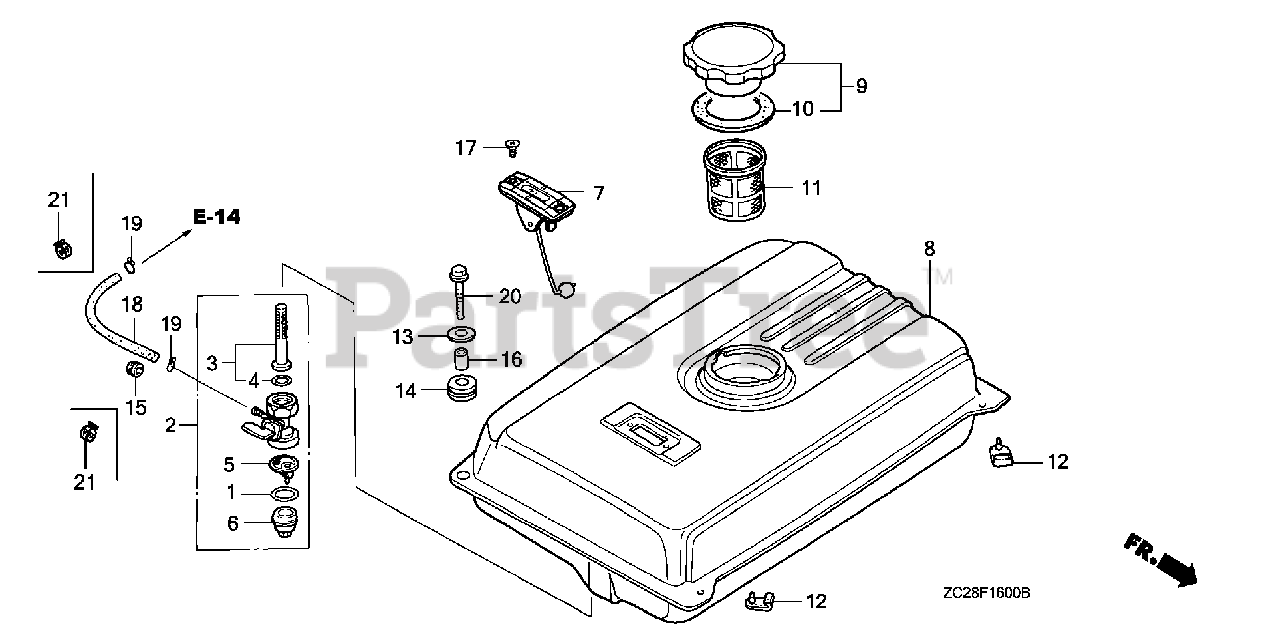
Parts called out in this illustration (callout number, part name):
1	GASKET, FUEL STRAINER CUP
2	PETCOCK ASSY.
3	SCREEN, FUEL STRAINER
4	O-RING (9X1.3)
5	FILTER, CUP
6	CUP, FUEL STRAINER
7	METER ASSY., FUEL
8	TANK, FUEL *R280* (POWER RED)
9	CAP, FUEL TANK
10	GASKET, FUEL FILLER CAP
11	FILTER, FUEL
12	RUBBER, TANK MOUNTING
13	WASHER, TANK RUBBER
14	CUSHION, TANK RUBBER
15	RUBBER, FUEL TUBE
16	COLLAR, TANK RUBBER
17	SCREW, FLAT (5X10)
18	BULK HOSE, FUEL (4.5X3000) (4.5X150)
19	CLIP, TUBE (B8)
20	BOLT, FLANGE (6X22)
20	BOLT, FLANGE (6X25)
